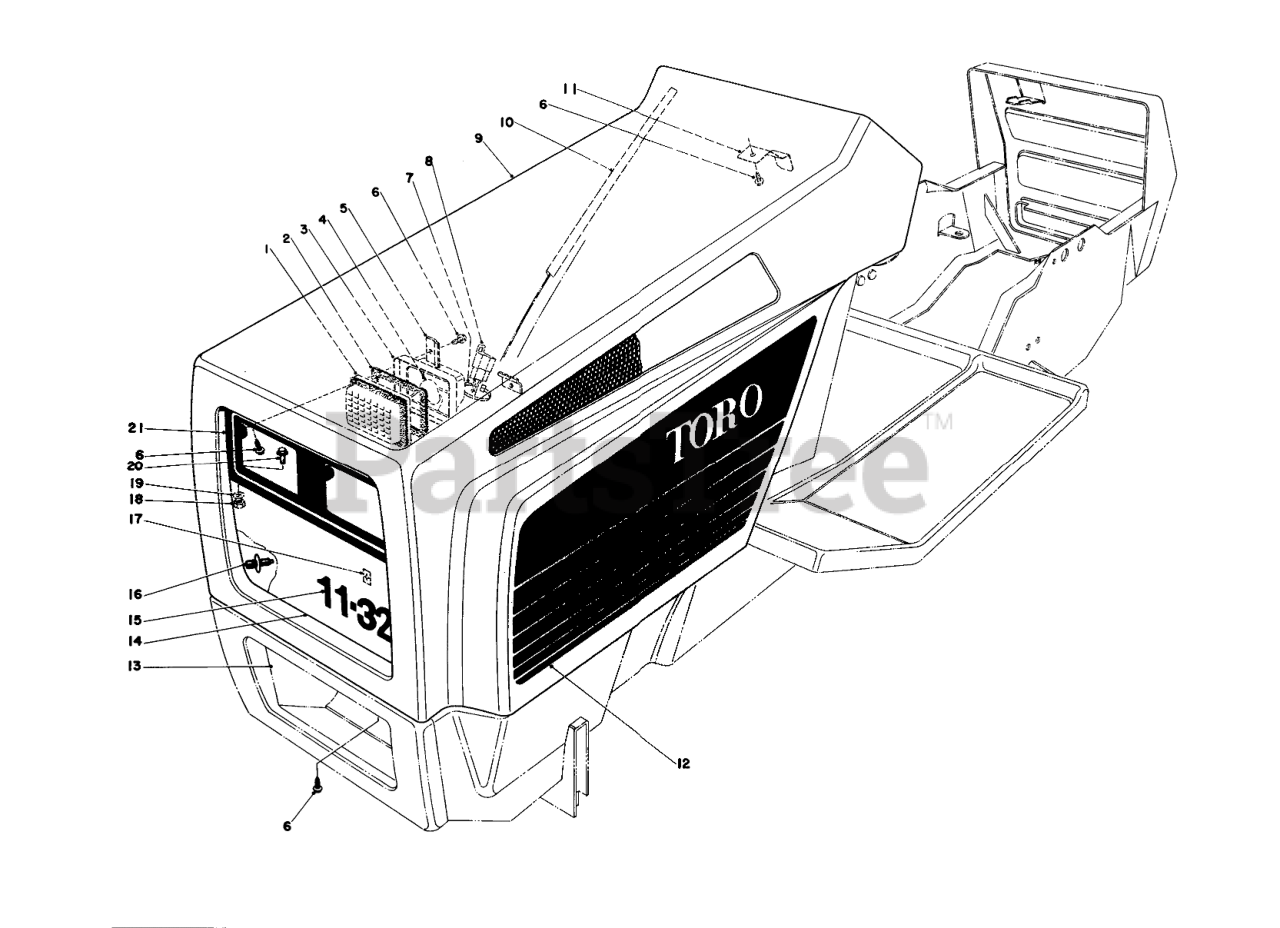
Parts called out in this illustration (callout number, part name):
1	Lens
2	Gasket Lens
3	Reflector
5	HEADLIGHT CLAMP
6	SCREW-HWHTF
7	TIE-CABLE
8	Connector
9	Hood Assy. (Incl. Ref. #12)
10	RUBBER EXT SEAL
11	SPRING LATCH
12	Decal Hood LH.
13	LOWER GRILLE
14	HEADLIGHT GRILLE
15	Name Plate-Grille
16	HINGE BRKT STUD
18	NUT-LOCK, SIDE
19	WASHER-FLAT
20	SCREW-SHWH
21	HEADLIGHT PANEL B
